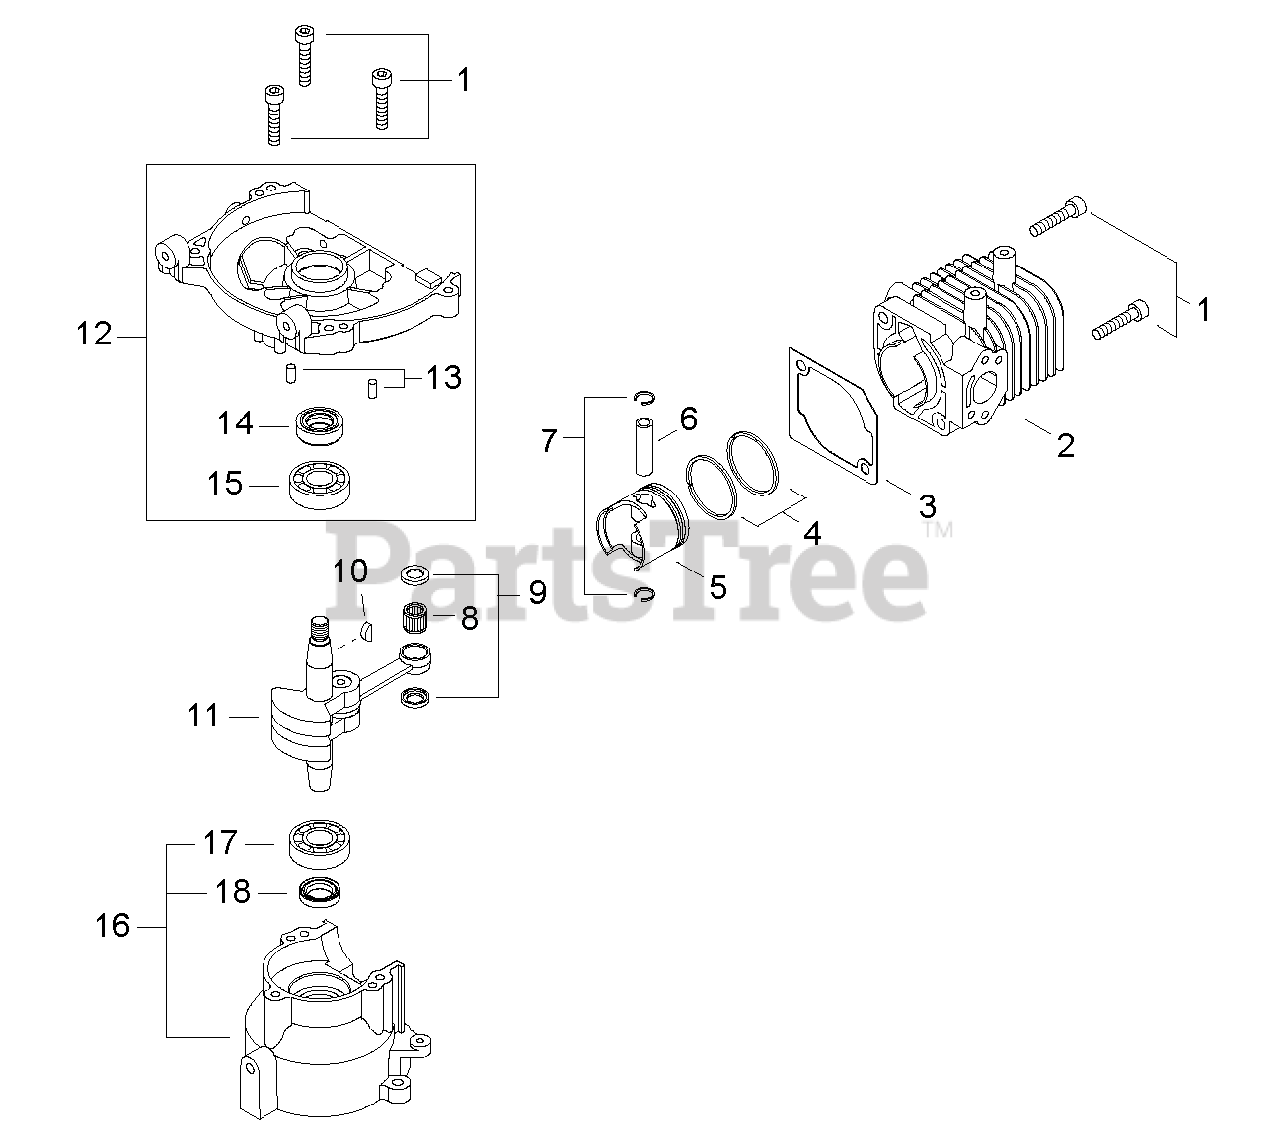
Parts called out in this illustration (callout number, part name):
1	SCREW - 5X25
2	CYLINDER
3	GASKET, CYLINDER
4	RING, PISTON
6	PIN, PISTON
7	RING, RETAINING
8	BEARING, NEEDLE - 8
9	SPACER, PISTON
10	KEY - 3X10
11	CRANKSHAFT ASSY
12	CRANKCASE ASSY - FRONT
13	PIN - LOCATING
14	SEAL, OIL - 12
15	BEARING, BALL - 6001C3
16	CRANKCASE ASSY
17	BEARING, BALL - 6001C3
18	SEAL, OIL - 12
